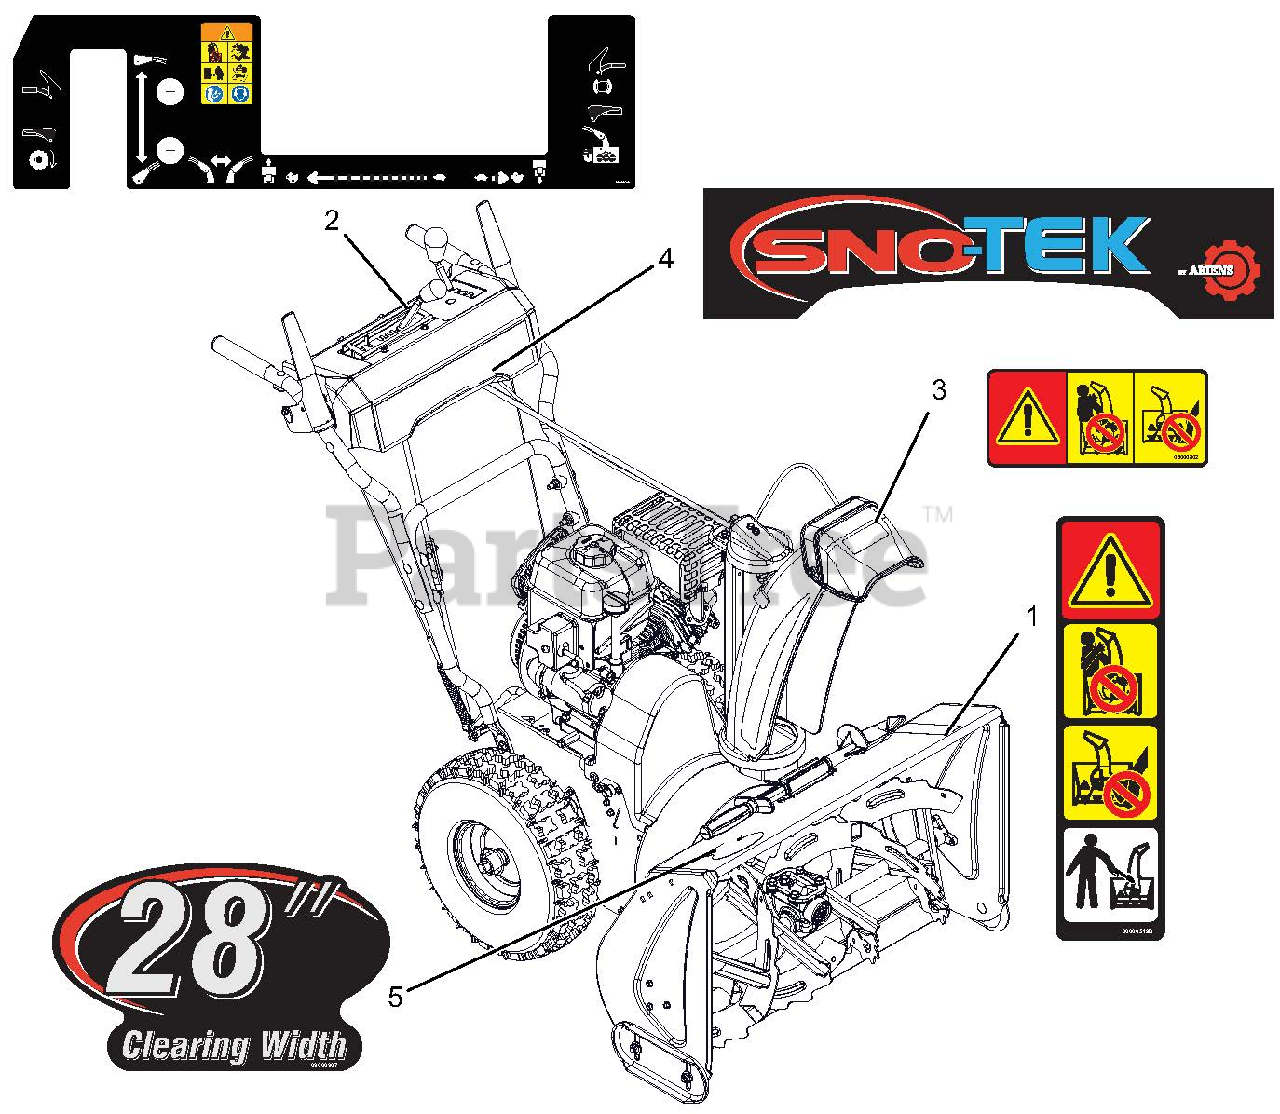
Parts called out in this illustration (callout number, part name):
1	DECAL, DANGER - ROTATING PARTS
2	DECAL,CONTROL - COMPACT REMOTE
3	DECAL, DANGER SNO-TEK
4	DECAL, DASH - SNO-TEK
5	DECAL, HOUSING SNO-TEK 28
